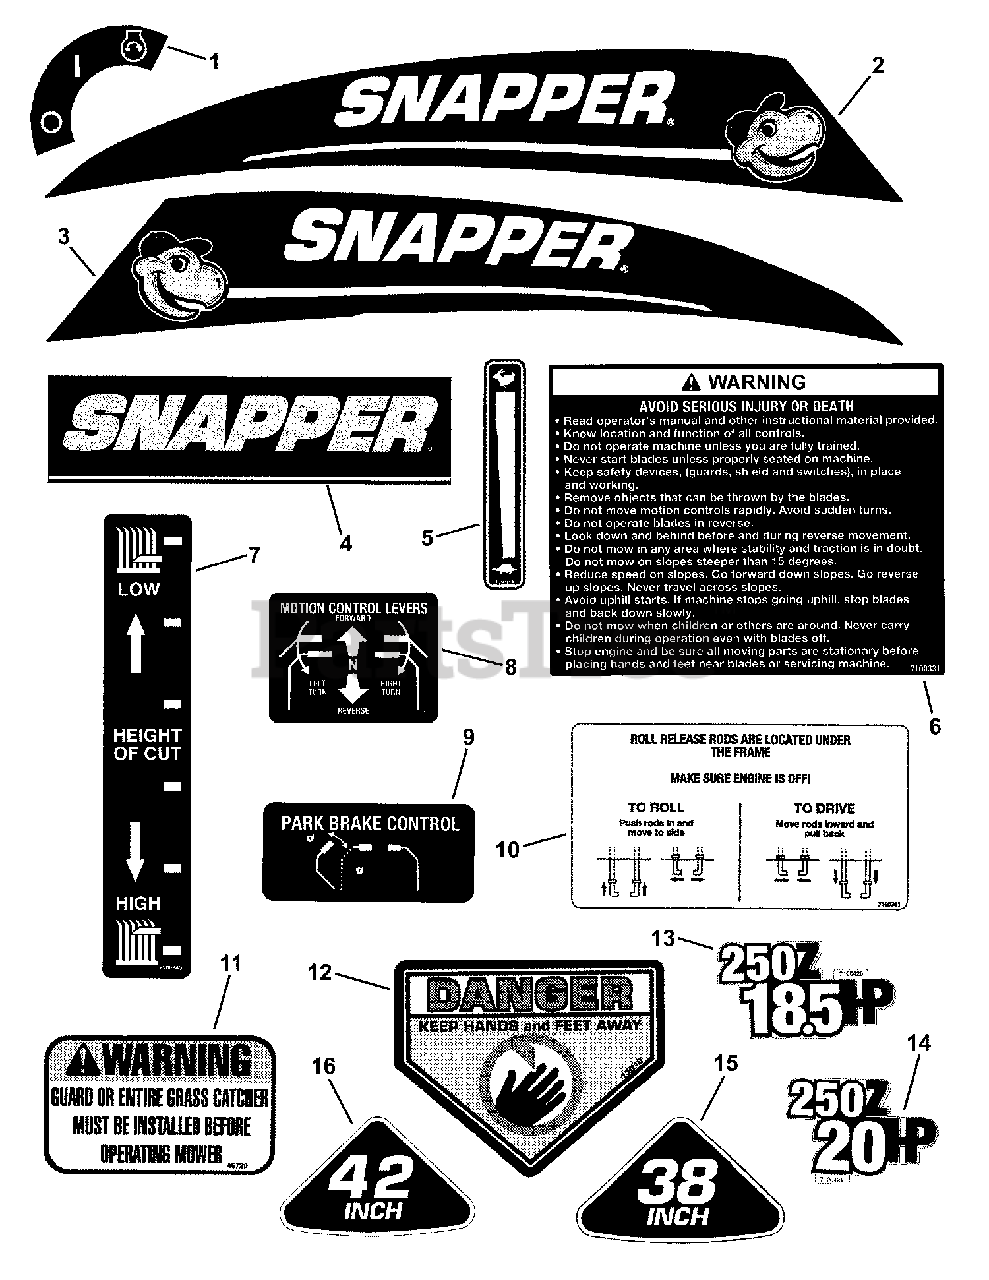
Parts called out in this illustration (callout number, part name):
1	DECAL, Ignition, RZT
2	DECAL, Snapper Fender, RH
3	DECAL, Snapper Fender, LH
4	DECAL, Snapper
5	DECAL, Throttle Control, RZT
6	DECAL, Warning, Operation
7	DECAL, Height Of Cut, RZT
8	DECAL, Motion Control, RZT
9	DECAL, Park Brake, RZT
10	DECAL, Roll Release, RZT
11	DECAL, Chute/Deflector
12	DECAL, Danger, (Cut Finger)
13	DECAL, 250 Z 18.5HP RZT
14	DECAL, 250 Z 20HP RZT
15	DECAL, 38 Inch
16	DECAL - 42 INCH
